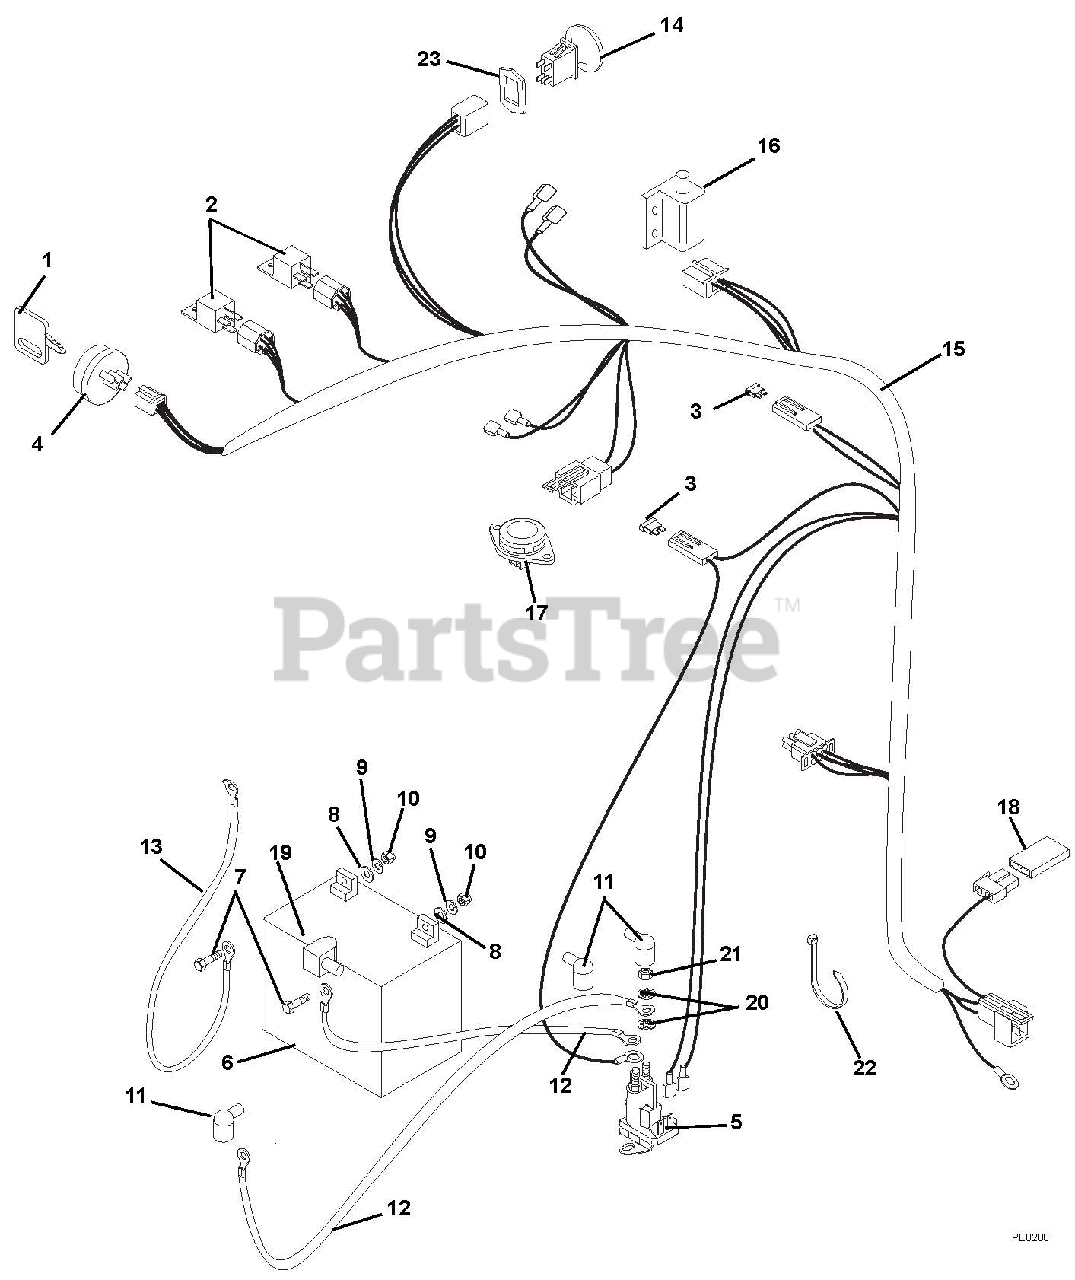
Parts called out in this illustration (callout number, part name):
1	Key with Cap
2	Relay
3	Fuse, 25 AMP
4	Key Switch
5	Solenoid
6	Battery, Filled
7	Bolt, Hex .25-20 x .75 Grade 5
8	Washer, Flat Steel .281 x .62 x .065
9	Washer, Locking .25 x .062 Regular
10	Nut, Hex .25-20
11	Boot, Eyelet Terminal
12	Starter Cable 13"
13	Ground Cable
14	Switch, Clutch With Retainer
15	Harness, Mini Zoom
16	Switch, Double Pole N.O. / N.O.
17	Switch, Snap Mounting (N.O.)
18	Diode, Connector Shell
19	Insulator
20	Washer, Locking .31
21	Nut, Jam .31-24
22	Cable Tie
23	Shim, PTO Switch
